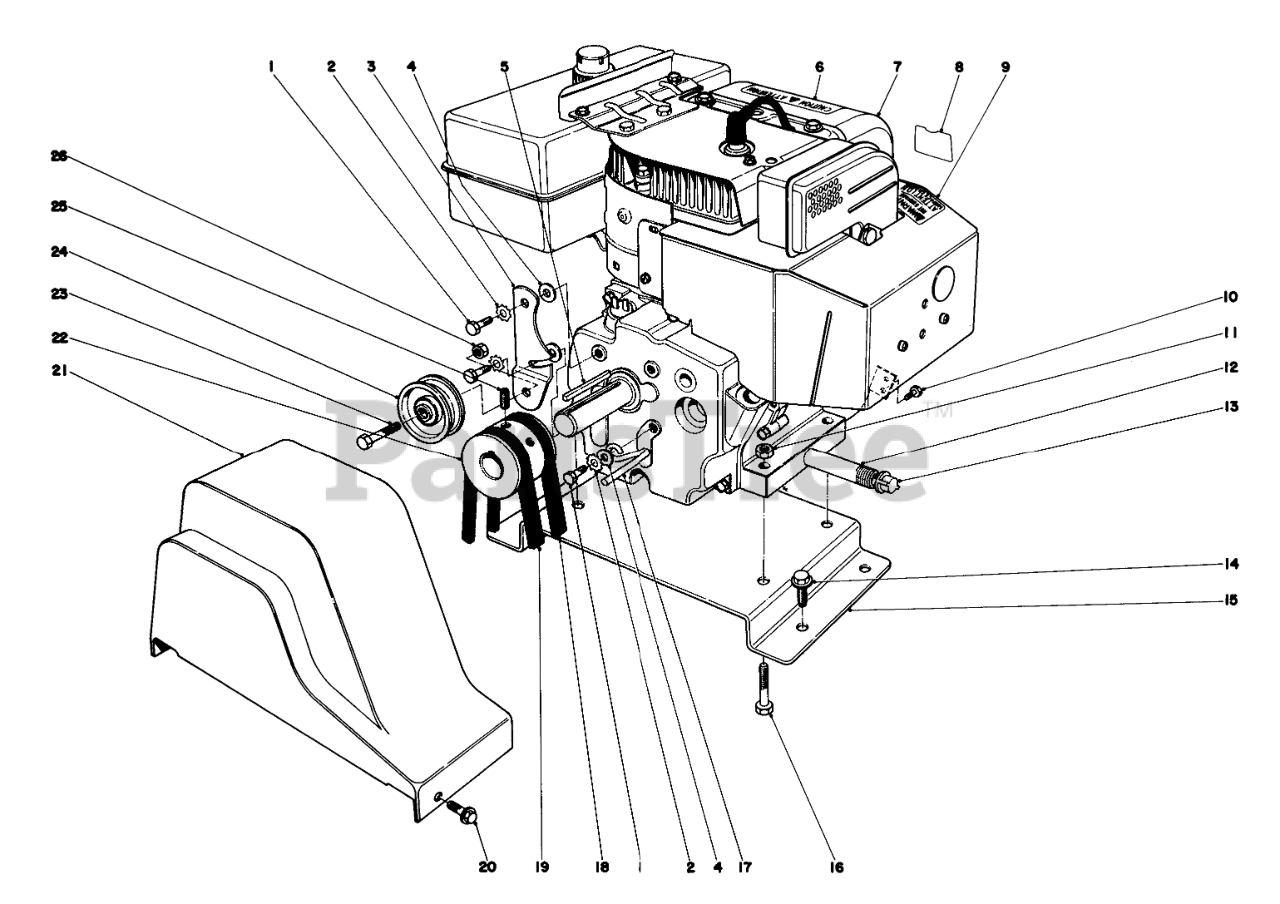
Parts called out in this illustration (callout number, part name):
1	SCREW-HH
2	WASHER-LOCK
4	WASHER-PLAIN
6	CAUTION DECAL
7	Engine
10	SCREW
11	NUT-LOCK, NI
12	NIPPLE-PIPE
13	CAP-PIPE
14	SCREW-HHFTF
16	SCREW-HH
18	V-BELT
19	V-BELT
20	SCREW-HWH
23	SCREW-HH
24	PULLEY-IDLER
